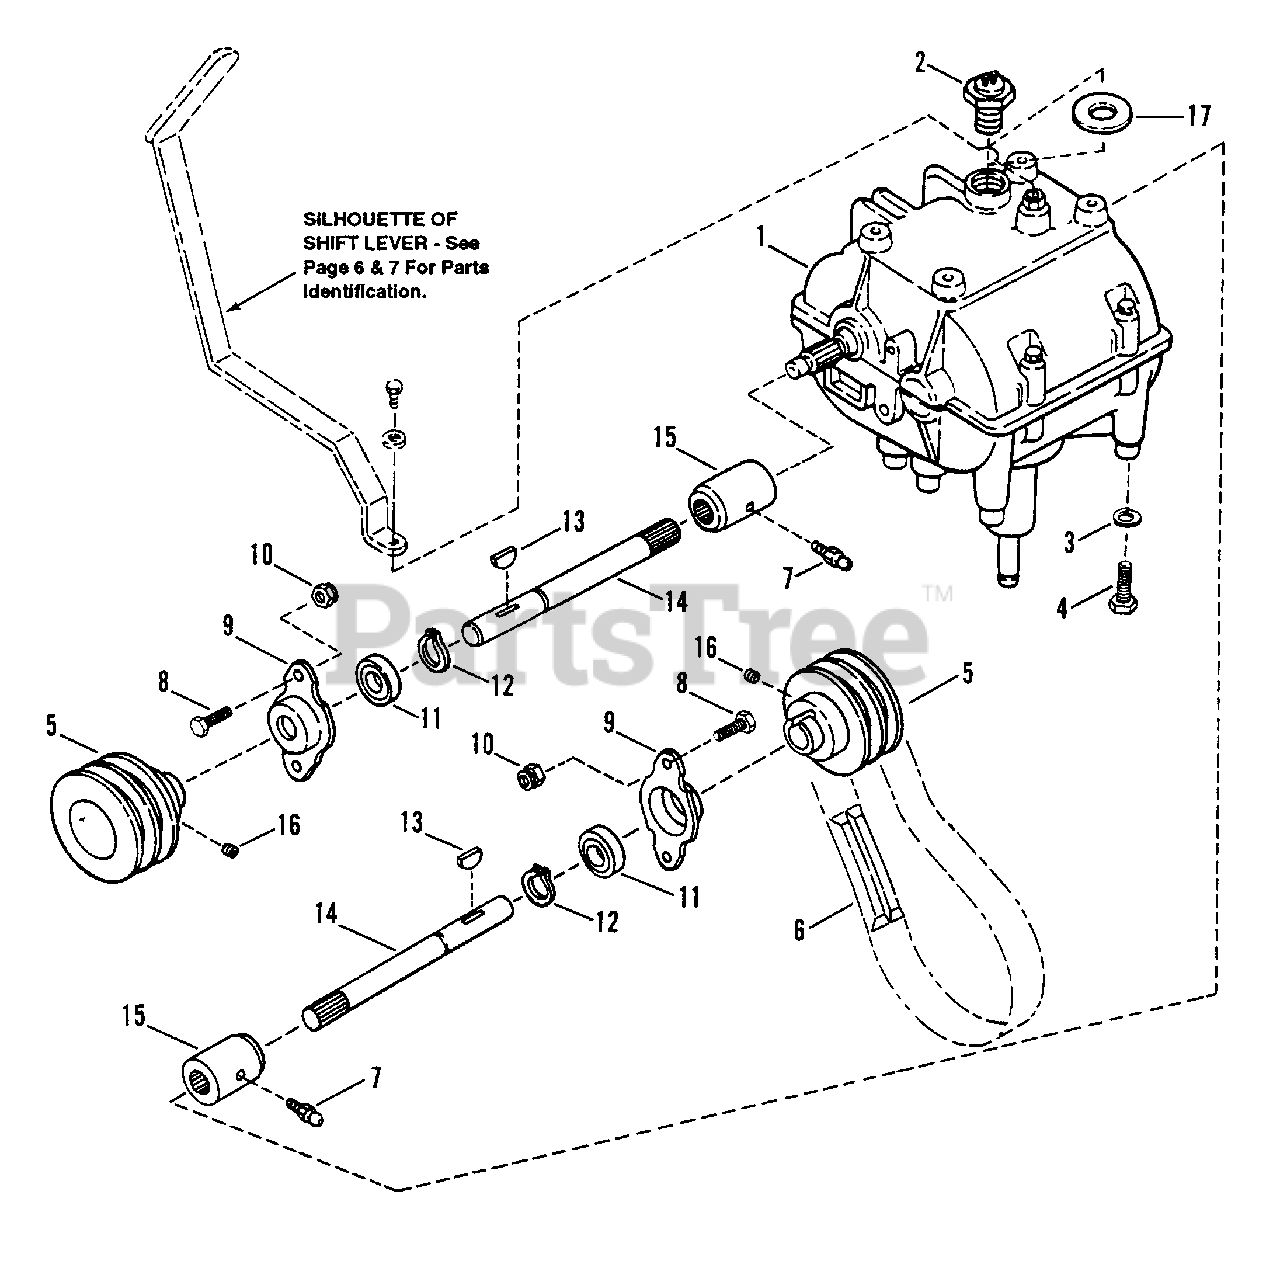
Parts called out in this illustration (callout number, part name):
1	TRANSMISSION
2	SWITCH, Transmission
3	WASHER, 5/16 Split Lock
4	BOLT, 5/16-18 x 3/4" Hex Head Cap
5	PULLEY, Output
6	BELT, Traction
7	FITTING, Lube
8	SCREW, 1/4-20 x 3/4" Hex Head Cap
9	FLANGE, Output
10	NUT, 1/4-20 Nyloc
11	BEARING, Output
12	RING, Retaining
13	KEY, #9 Woodruff
14	SHAFT, Output
15	COUPLER
16	SCREW, 5/16-18 x 3/8" Knurled Cup Point Set
17	WASHER, Fiber
